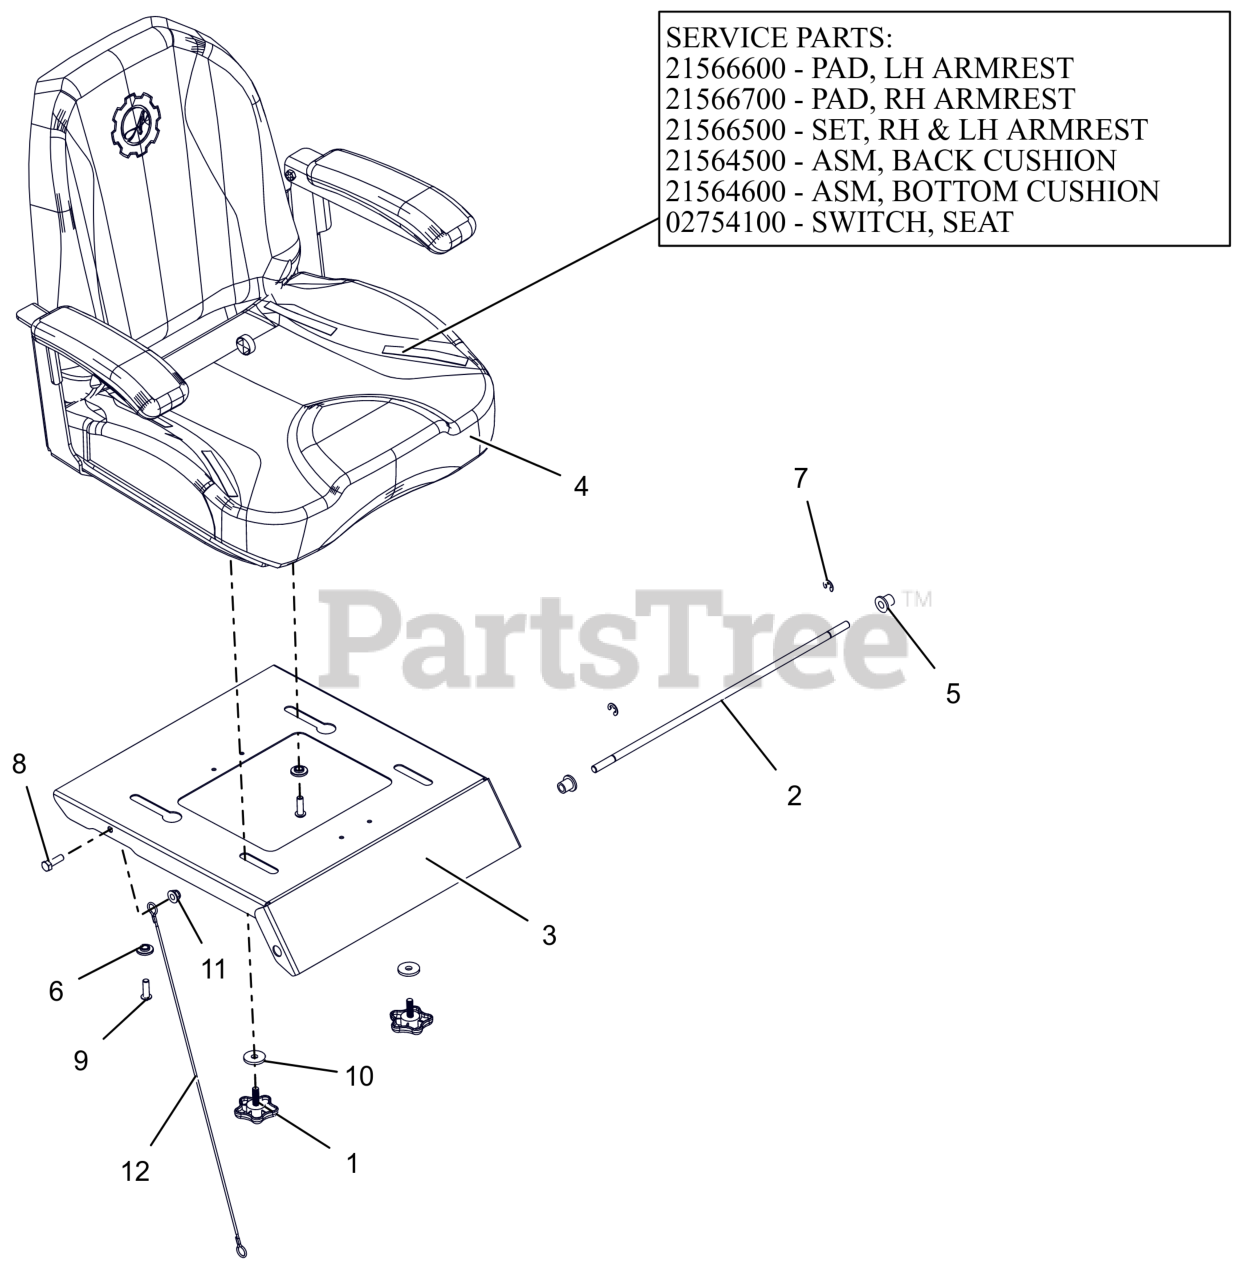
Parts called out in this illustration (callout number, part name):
1	KNOB, WING STUDDED
2	ROD, SEAT PIVOT
3	PLATE, SEAT (FASTENER SLIDE)
4	SEAT, IKON
4	PAD, LH ARMREST
4	PAD, RH ARMREST
4	SET, RH & LH ARMREST ASM
4	ASM, BACK CUSHION-ARIENS X
4	ASM, BOTTOM CUSHION-ARIENS X
4	SWITCH- SNAP MTG N.O.
5	BSHG-FLG .38X.580X.667X.750
6	BSHG, FLG .312X.499X.23X.88
7	RG-RTNG-EXT .375X.035 TYP E
8	BLT,HEX .31-18X1.00 G5 ZCC
9	BLT,SHCS-BTN .31-18X1.00 ZCC
10	WSHR, FLT .340X1.125X.135 ZCC
11	NUT,LK-NYL-FLG .31-18 G5ZC120
12	LANYARD, SEAT CABLE .093X19.5
